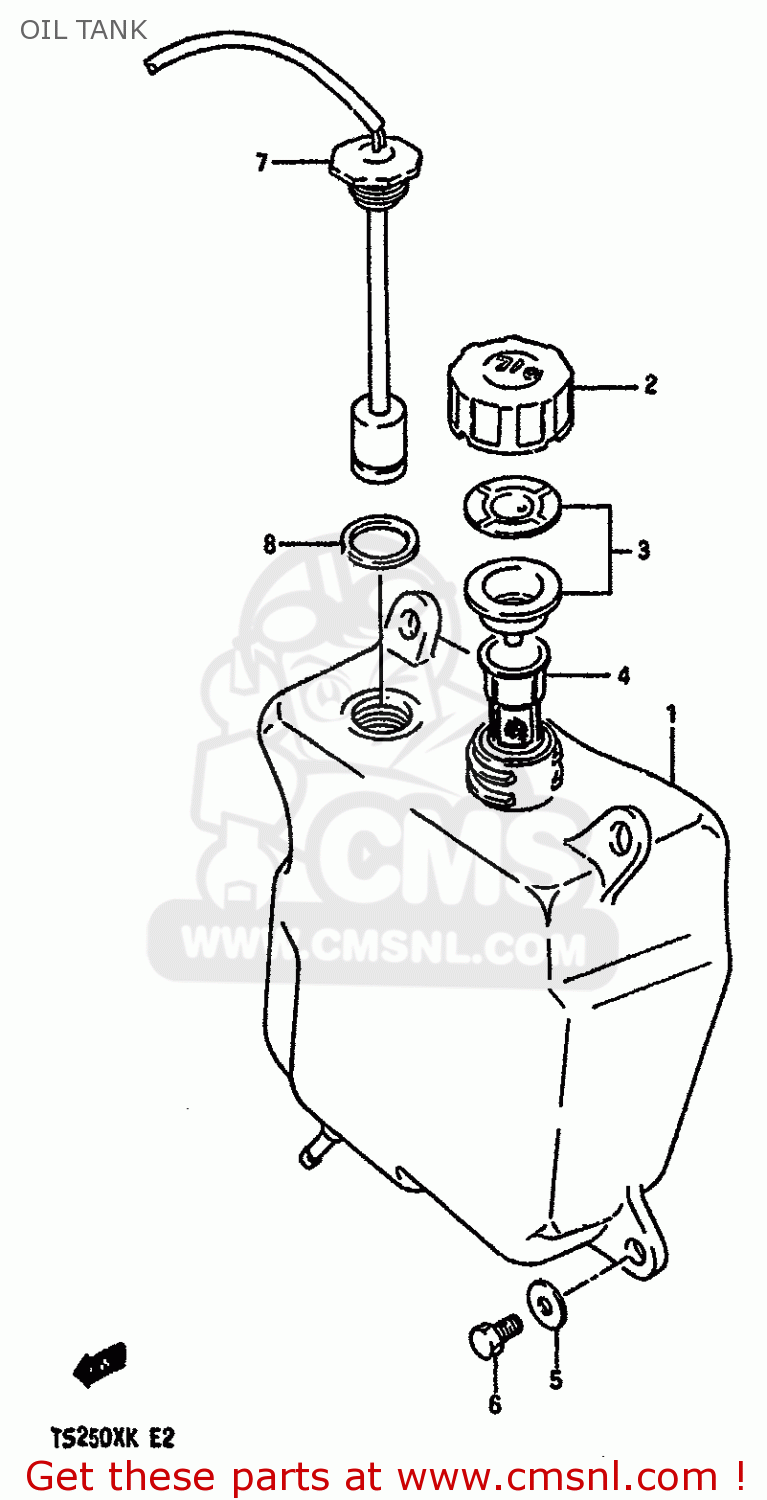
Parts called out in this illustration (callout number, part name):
1	TANK,OIL
2	CAP,OIL TANK
3	GASKET SET (NAS)
4	NET,OIL TANK
5	WASHER
6	BOLT
7	SWITCH ASSY, OIL LEVEL
8	GASKET (NAS)
